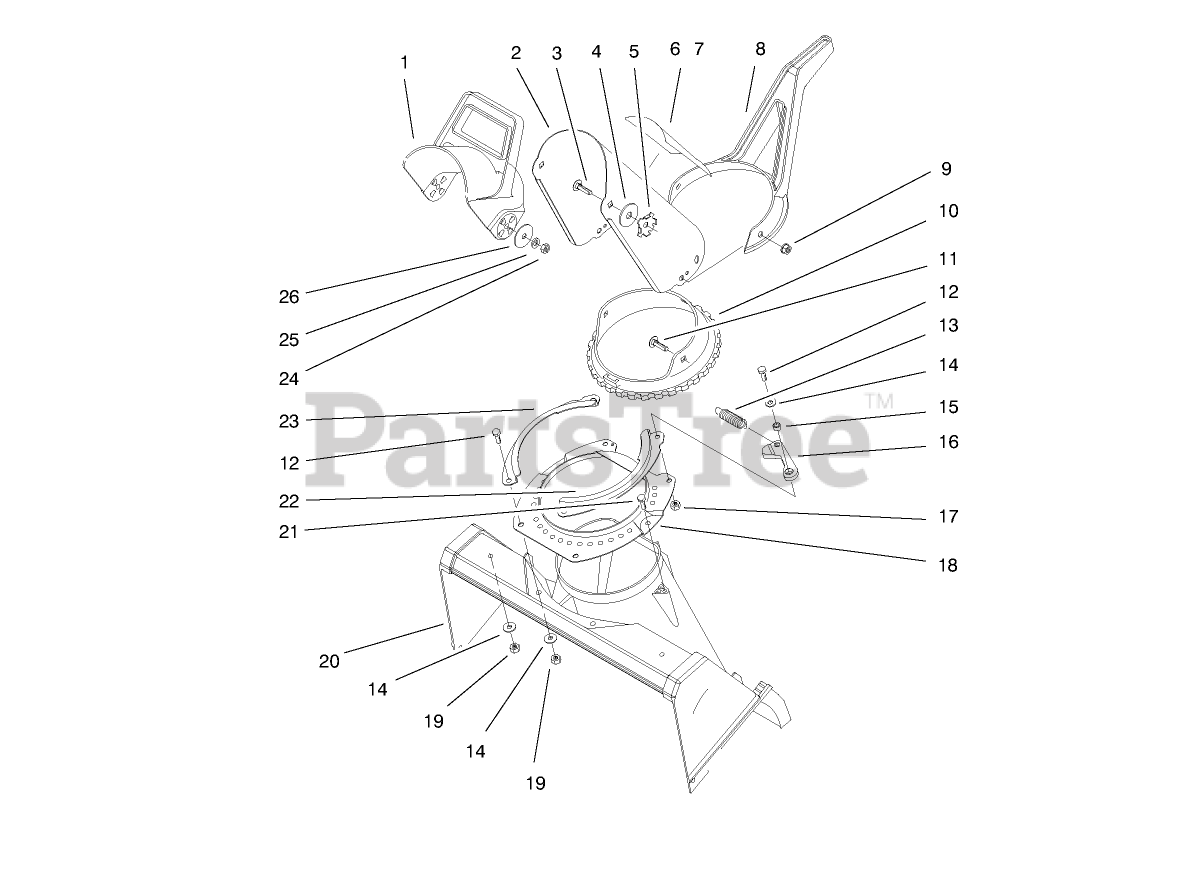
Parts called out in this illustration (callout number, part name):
1	CHUTE-DEFLECTOR
2	CHUTE ASM
3	SCREW-CARR
4	WASHER-RUBBER
5	PLATE-FRICTION
7	DECAL-DANGER
8	HANDLE-CONTROL, CHUTE
9	NUT-KEPS
10	GEAR RING, CHUTE
11	SCREW-CARR
12	SCREW-HH
13	SPRING-EXTENSION
14	WASHER-FLAT
15	SPACER-BLADE, ROTOR
16	DETENT
17	NUT-LOCK, NI
19	NUT-LOCK, NI
21	SCREW-PLASTITE
24	NUT-LOCK, NI
25	WASHER-BELLEVILLE
26	WASHER-FLAT
